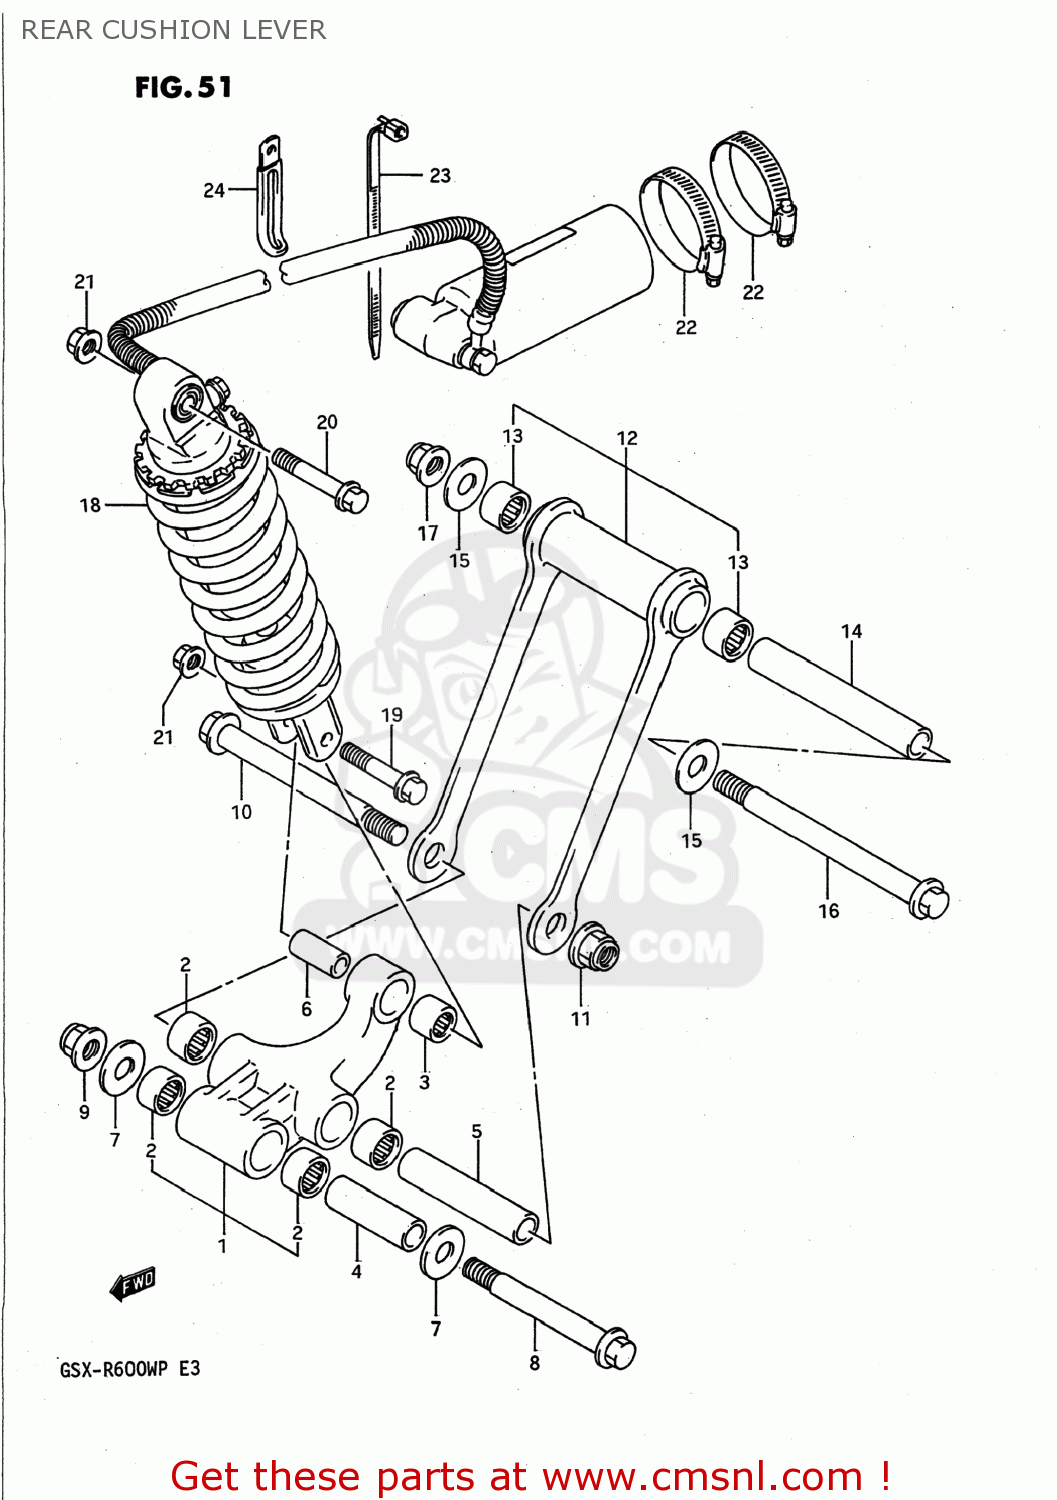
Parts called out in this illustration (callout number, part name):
1	LEVER SET,REAR CUSHION
2	BEARING(20X27X23.5)
3	BEARING(17X24X26)
4	SPACER,RR CUSHION LEVER
5	SPACER,RR CUSHION ROD
6	SPACER,RR CUSHION LEVER
7	WASHER
8	SHAFT,RR CUSHION LEVER FR
9	NUT
10	SHAFT,RR CUSHION ROD
11	NUT
12	ROD SET,RR CUSHION LEVER
13	BEARING(20X27X23.5)
14	SPACER (14X20X122)
15	WASHER
16	BOLT(14X161)
17	NUT
18	ABSORBER ASSEMBLY,REAR SHOCK
19	BOLT(10X58)
20	BOLT(10X75)
21	NUT
22	CLAMP
23	CLAMP(L:165)
24	CLAMP
